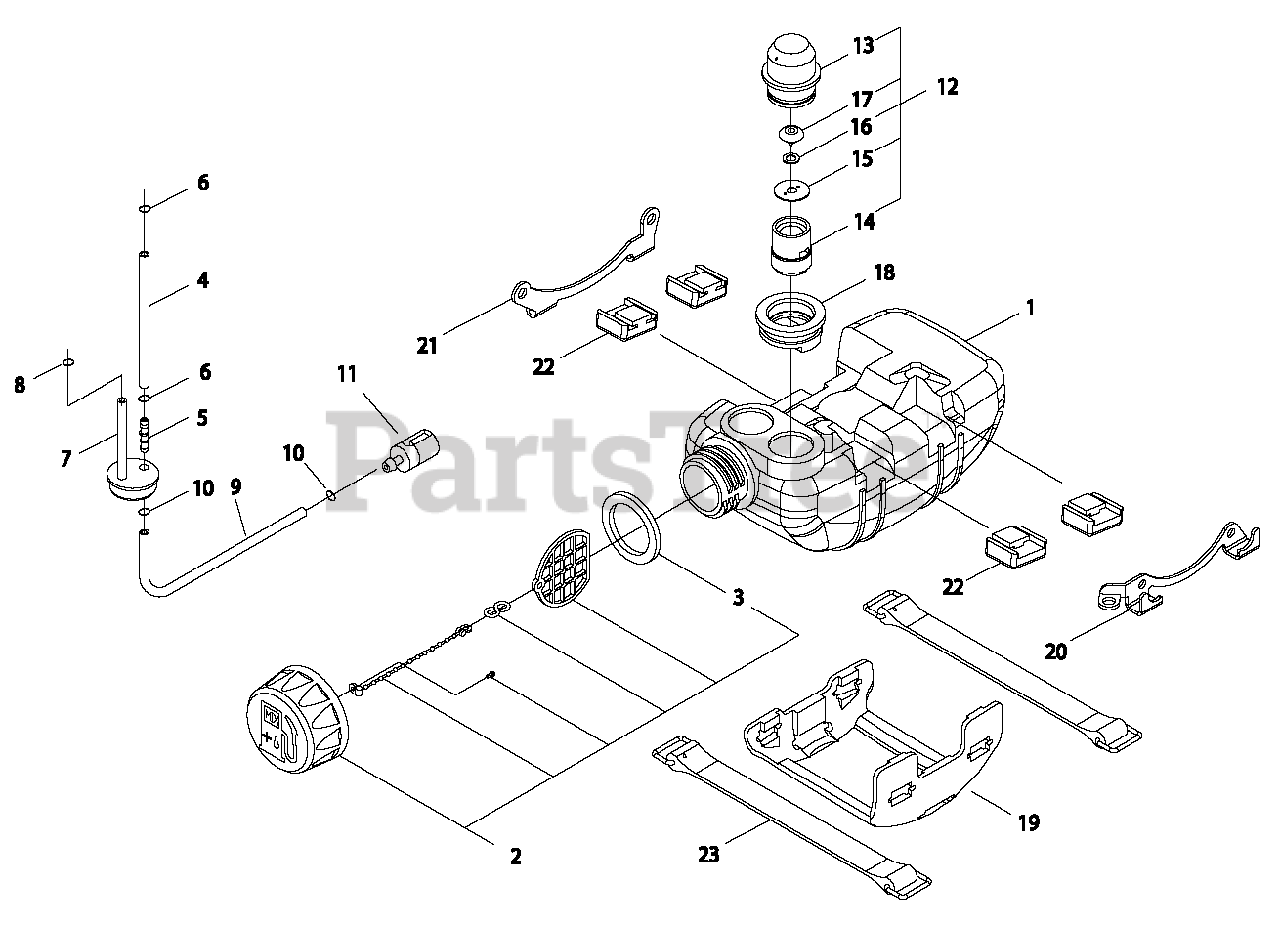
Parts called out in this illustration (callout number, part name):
1	TANK, FUEL
2	CAP ASSY - RED
3	GASKET, CAP
4	PIPE - FUEL
5	CONNECTOR, PIPE
6	CLIP - 6
7	GROMMET
8	CLIP - 6
9	PIPE - FUEL
10	CLIP - 6
11	FUEL FILTER ASSY
12	VENT ASSY
13	CAP, BREATHER
14	HOLDER, VENT
15	RETAINER
16	WASHER
17	VENT, FUEL TANK
18	GROMMET
19	GUARD, FUEL TANK
20	BRACKET - OUTER
21	BRACKET - INNER
22	CUSHION
23	STRAP, FUEL TANK
